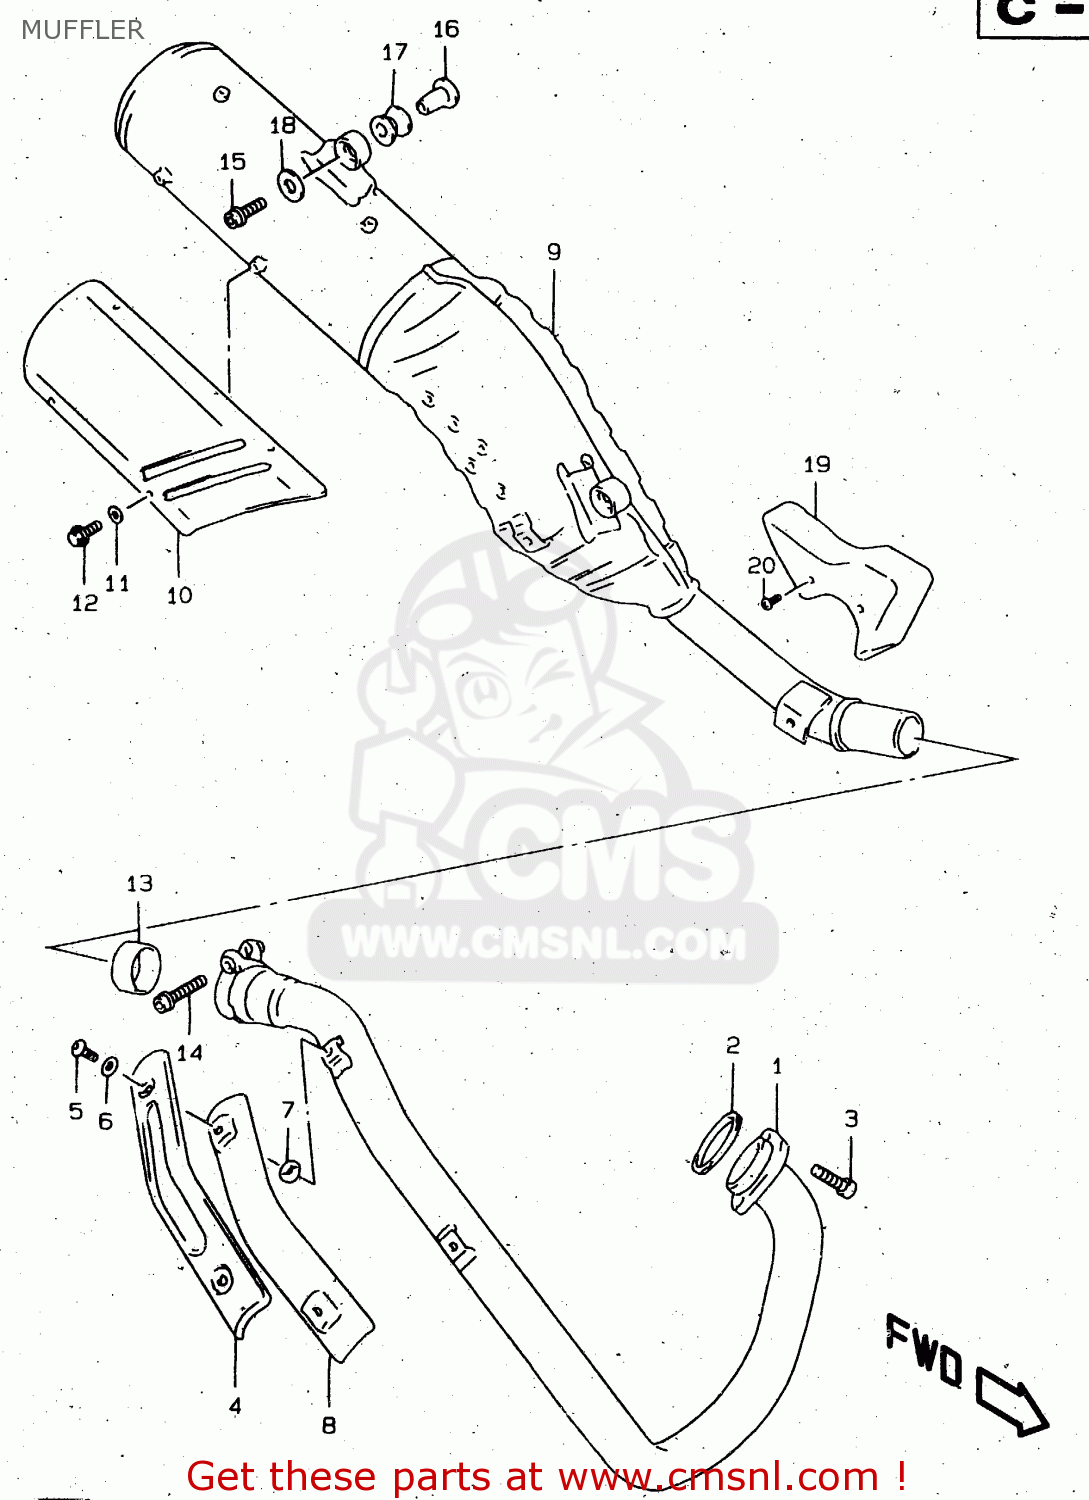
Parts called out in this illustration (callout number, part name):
1	PIPE COMP,EXHAUST
2	GASKET,EXHAUST PIPE (NAS)
3	BOLT
4	COVER,EXHAUST PIPE
5	SCREW(6X12)
6	WASHER(6.5X13X1.0)
7	GASKET(6X16X1.4) (NAS)
8	COVER,EXHAUST PIPE INNER
9	BODY, MUFFLER
10	COVER,MUFFLER
11	WASHER(6.5X13X1.0)
12	SCREW(6X10)
13	CONNECTOR,MUFFLER
14	BOLT
15	BOLT(8X30)
16	SPACER(8.6X12X17.5)
17	CUSHION
18	WASHER(8.5X28X1.6)
19	COVER,CONNECTOR CLAMP
20	SCREW(6X10)
